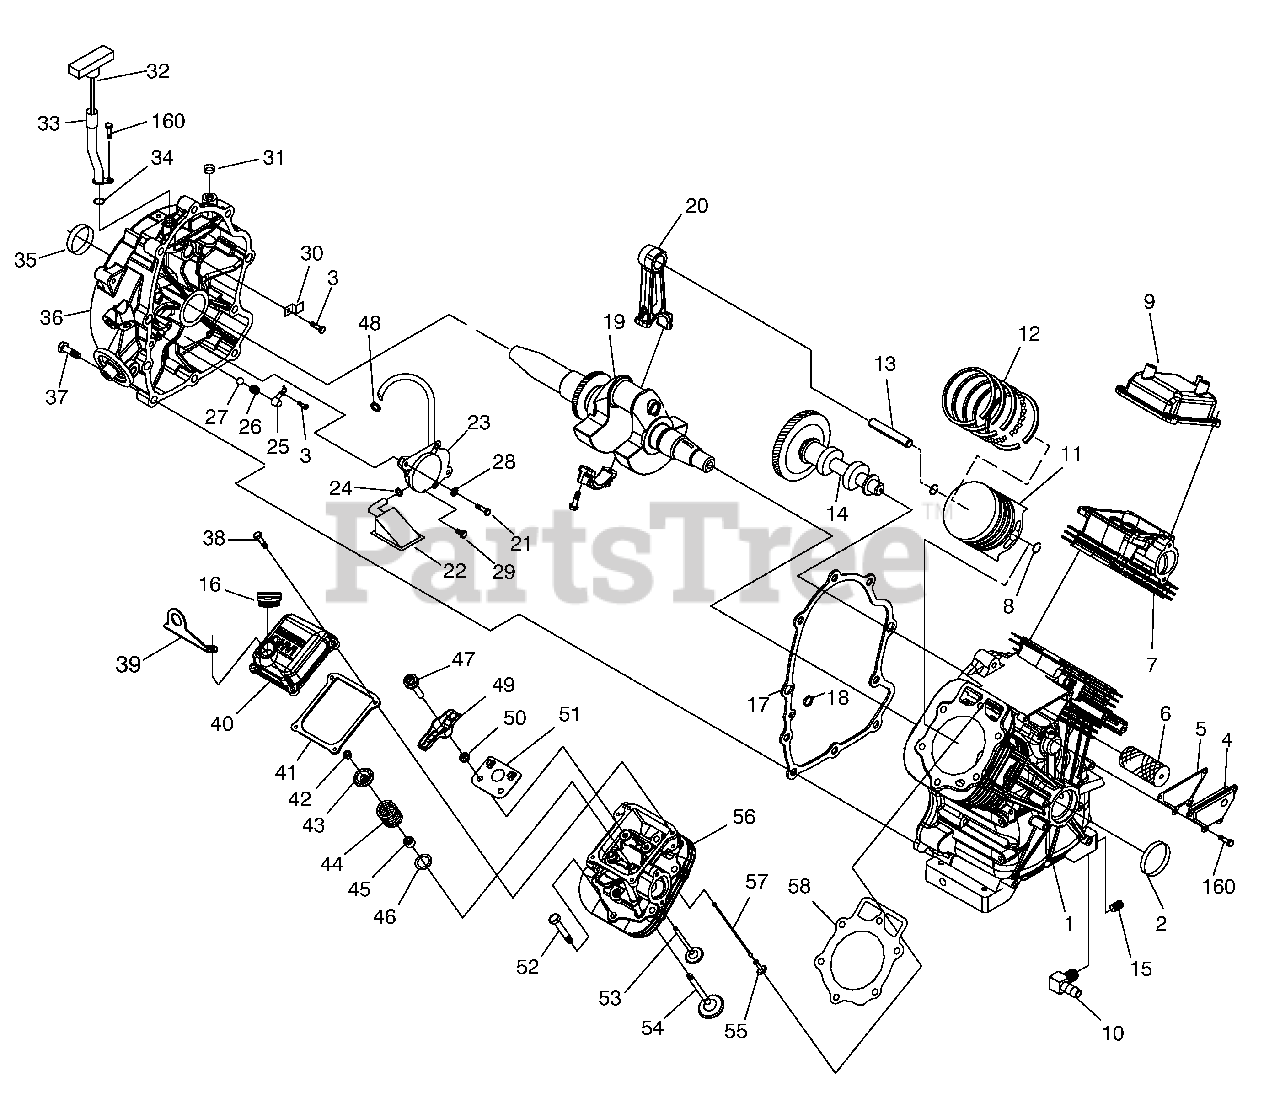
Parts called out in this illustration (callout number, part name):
1	ASSEMBLY, CRANKCASE HOUSING WITH SLEEVE
2	SEAL, 38 I.D. CRANKSHAFT
3	SCREW, TAPTITE M6-1.0 X 12 BP
4	ASSEMBLY, BREATHER
5	GASKET, BREATHER COVER
6	SEPARATOR, OIL BREATHER
7	ASSEMBLY, HEAD #1
8	RETAINER, PISTON PIN 20
9	ASSY,ROCKER COVER W/BARB
10	BARBED EL 90 3/8NPT X 3/8
11	PISTON, LC (GT-990)
12	SET, PISTON RING 90MM
13	PIN PISTON
14	ASSEMBLY, CAMSHAFT & GEAR
15	PLUG STD PIPE 3/8 STEEL SQ HD
16	ASSEMBLY, OIL FILL CAP
17	GASKET, CRANK CASE
18	SEAL, OIL PASSAGE
19	ASSEMBLY, CRANKSHAFT HORIZONTAL DIRECT DRIVE (GT-990)
20	ASSEMBLY, CONNECTING ROD (GT-990)
21	SCREW SHC M6-1.0 X 50 G8.8
22	SCREEN, OIL PICKUP
23	ASSEMBLY, OIL PUMP
24	O-RING, 0.49 ID X 0.07 THICK
25	COVER, OIL RELIEF
26	SPRING, OIL RELIEF
27	BALL, 1/2D OIL RELIEF
28	WASHER, LOCK RIB M6
29	SCREW, PLASTITE HI-LOW #10
30	CLAMP, OIL TUBE
31	PLUG-CRANKCASE GOVERNOR BORE
32	ASSEMBLY, DIPSTICK WITH HANDLE
33	TUBE, DIPSTICK
34	O-RING, OIL CLR
35	SEAL, 42 I.D. CRANKSHAFT
36	ASSY, GEAR COVER / ADAPTOR W/SLEEVE
37	SCREW, HHFC M10-1.5 X 55
38	SCREW HHFC M6-1.0 X 25
39	LIFT HOOK, GT990/760
40	COVER,ROCKER W/OIL FILL "GENERAC" TEXT
41	GASKET, VALVE COVER
42	KEEPER, VALVE SPRING
43	RETAINER, VALVE SPRING
44	SPRING, VALVE
45	SEAL, VALVE STEM D7
46	WASHER, VALVE SPRING
47	STUD, ROCKER ARM PIVOT
48	O-RING, 3/8" X 1/2"
49	ROCKER ARM
50	NUT, HEX M8-1.0 GB YELLOW CHROM
51	PLATE, PUSH ROD GUIDE
52	SCREW HHFC M8-1.25 X 65
53	VALVE, EXHAUST
54	VALVE, INTAKE
55	TAPPET, SOLID
56	ASSEMBLY, HEAD #2
57	PUSHROD 147
58	GASKET, HEAD
59	KIT GEAR COVER
60	KIT GASKET
61	KIT PISTON & RINGS
62	KIT BREATHER ASSEMBLY
63	KIT HEAD ASSEMBLY CYLINDER 1
64	KIT HEAD ASSEMBLY CYLINDER 2
65	KIT OIL RELIEF
